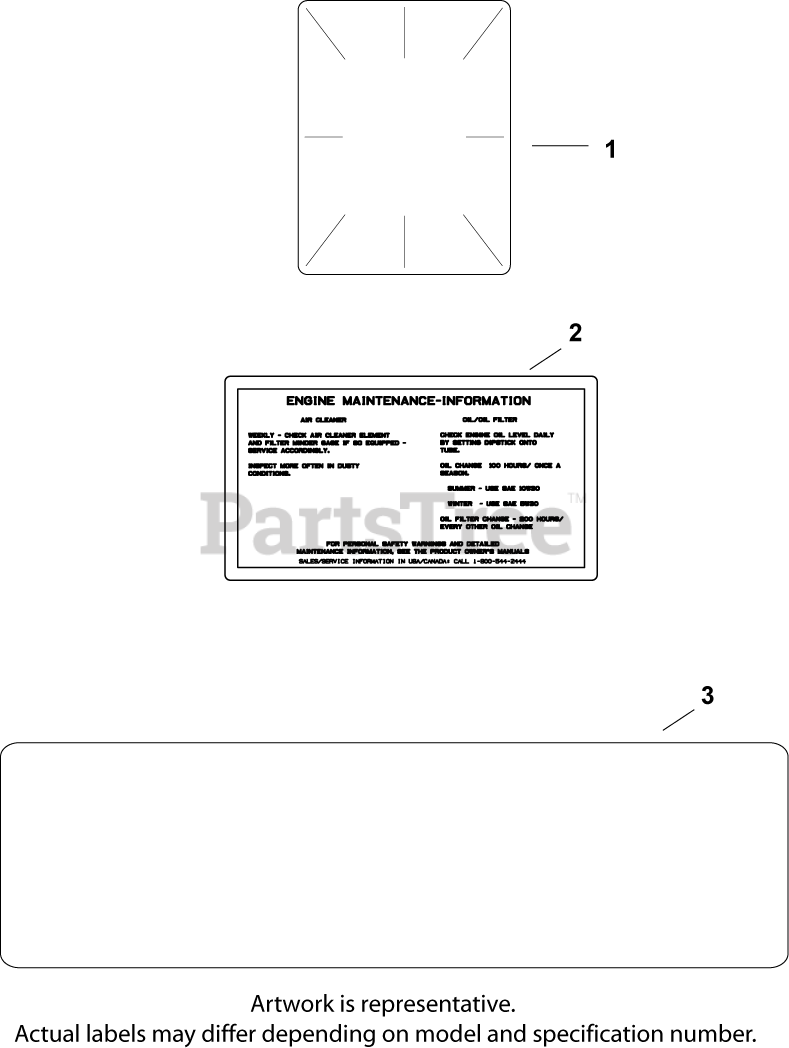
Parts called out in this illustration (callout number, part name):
1	DECAL, CLEAR LAMINATE USE 25 113 70-S
2	DECAL, AIR CLEANER - (#DSC)
3	DECAL, 18 HP
